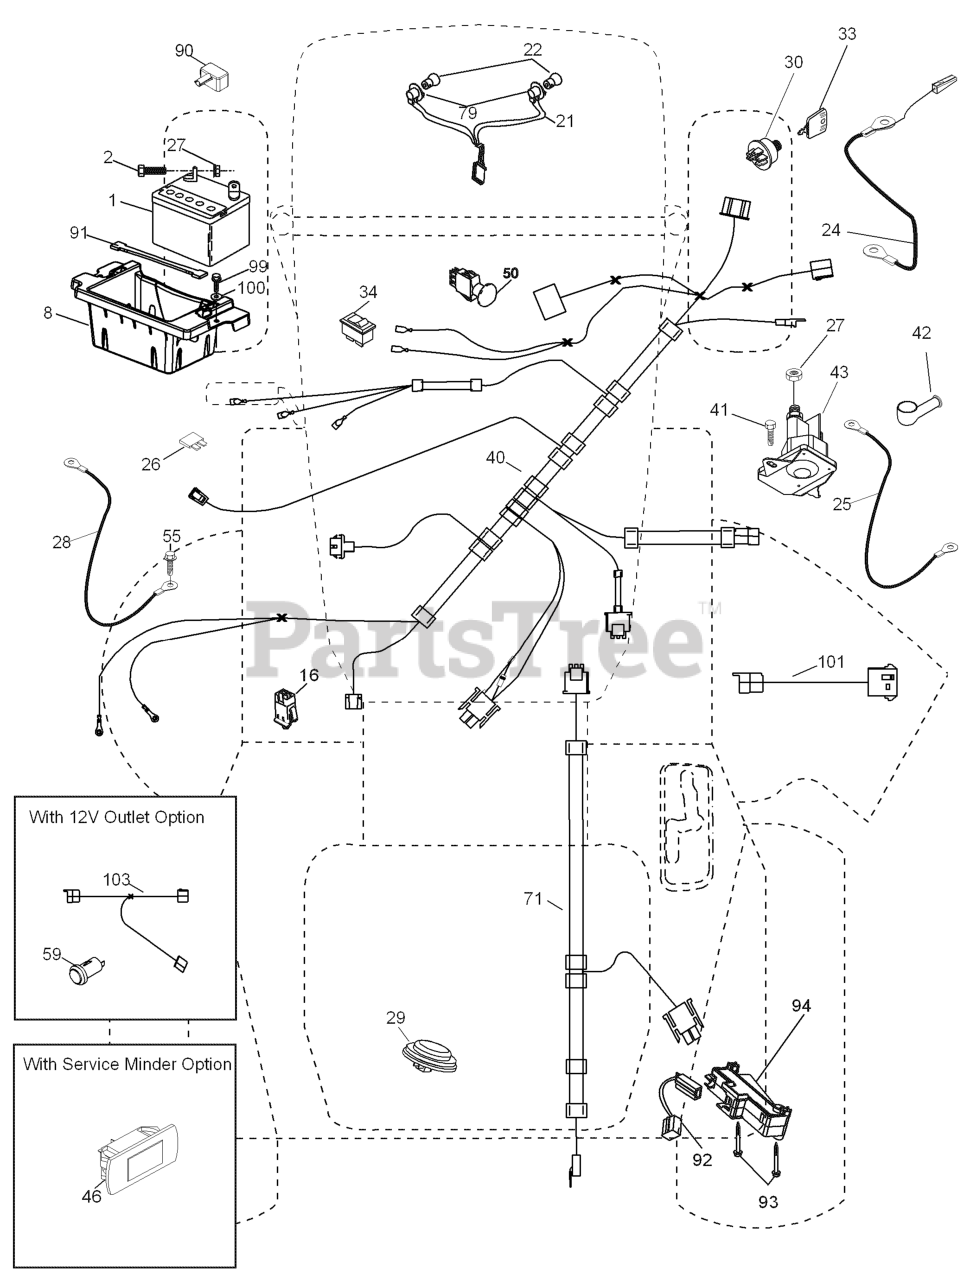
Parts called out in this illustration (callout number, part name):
1	Battery
2	BOLT.HEX.1/4.X.3/4.DICHROMATE
8	BOX.BATTERY.MOUNT.FRONT.LT
16	SWITCH INTERLOOK PUSH-IN
21	HARNESS ASSY LIGHT
22	Bulb, Light
24	CABLE.BATT.POS.WIRE.TG.DA SOL
25	CABLE.STARTER.6G.BL/RED.17.5
26	FUSE 20AMP
27	NUT
28	CABLE GROUND 6 GA 21" 90T BLK
29	SWITCH.SEAT.DELTA.OPC.
30	SWITCH.IGN.DELTA.W.LGH.ROS
33	KEY.CHAIN.BLISTER.PACK.GEN.INT
40	HARNESS.IGN.DASH.HUQ/P
41	SCREW
42	TERMINAL COVER
43	SOLENOID.W/BRASS.PLUNGER
46	RP.GUAGE.SRVCMNDR.HRMTR.
50	RP.PTO.SWITCH.8 TERMINAL.BLACK
55	SCREW 5/16"
59	OUTLET.12-VOLT
71	HARNESS-CHASSIS SUB
79	BULB HOLDER ASM.
90	COVER.TERMINAL.BATTERY
91	STRAP.BATTERY.MOUNT.FRONT(2 2)
92	HARNESS.PIGTAIL.CONSLE
93	SCREW.PLASTITE
94	MODULE.REVERSE.ROS
99	SCREW HEXWSHR 1/4-20X3/4
100	WASHER
101	PIGTAIL.MATNLK.NEW.HAR
103	HARNESS PIGTAIL 12V OUTLET
